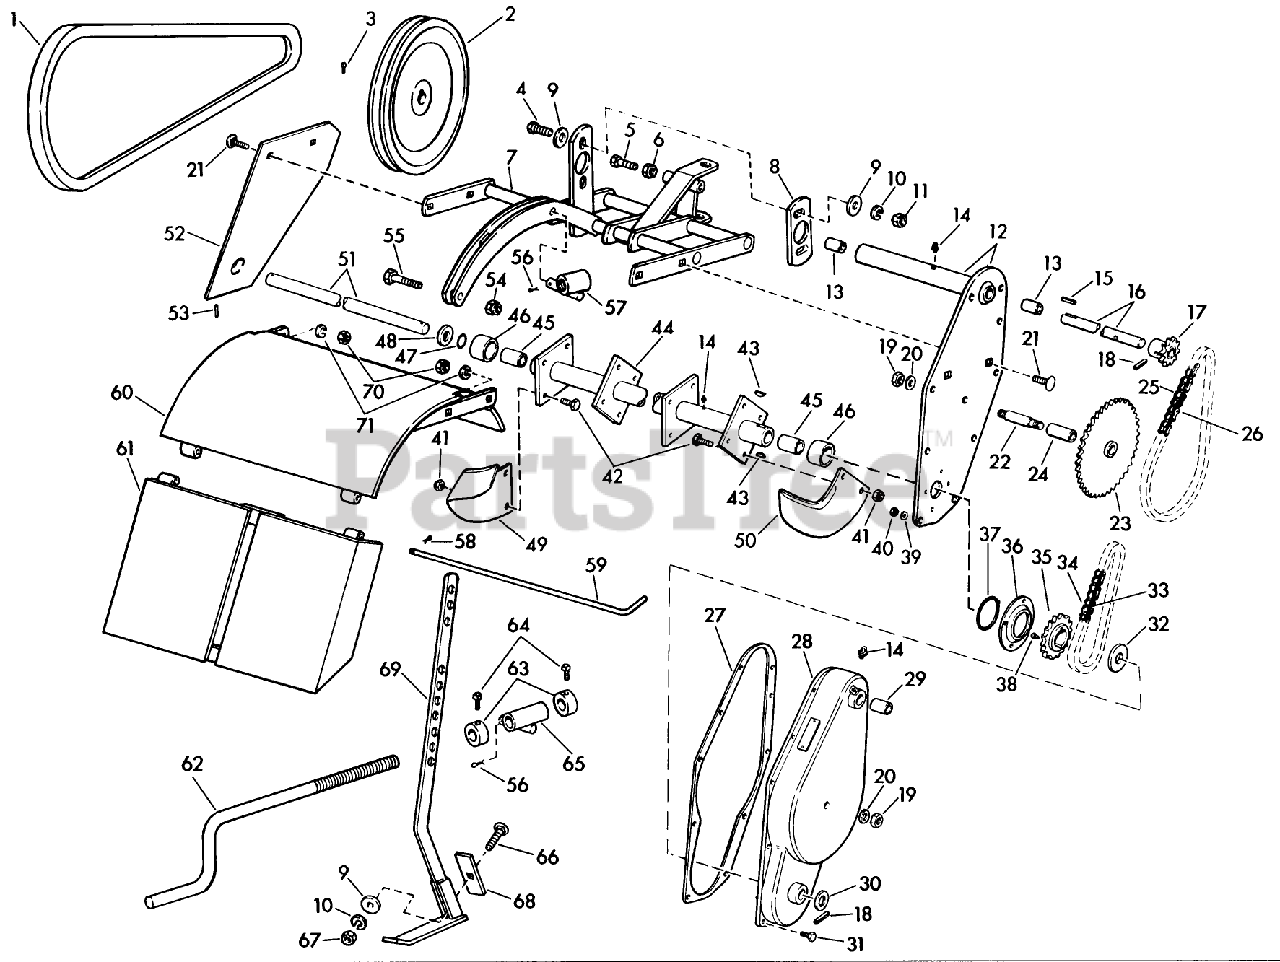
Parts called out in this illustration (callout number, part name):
1	V Belt 60" A Section
2	Pulley 10.4 OD A Section
3	Set Screw
4	Capscrew 5/16-18 x 7/8 Lg.
5	Capscrew 3/8-16 x 1 Lg.
6	Hex Nut 3/8-16
7	Frame Assembly
9	BAR-LIFT LINK *R
10	Lockwasher
11	Hex Nut
12	Back Plate Assembly
14	Grease Fitting
16	Input Shaft
17	Input Sprocket and Hub Assv.
18	Roll Pin
19	Hex Jam Nut
20	Lockwasher, Shakeproof
21	PEDAL-BRAKE *R
22	Intermediate Shaft
23	Sprocket Cluster Assy
24	Bushing
25	Chain #41-1/2 Pitch, 55 Links
28	Cover Assembly
31	Capscrew
32	Thrust Washer
33	Extension-Chute
36	Oil Seal Retainer
38	Self Tapping Screw #8-32 x 1/4 Lg.
40	Hex Nut
44	Rotor Tube Assembly
49	Tine LH
51	Rotor Shaft
52	Side Plate Assembly
53	Roll Pin
55	Capscrew 3/8-24 x 2 Lg.
56	Cotter Pin 1/8 x 1-1/2 Lg.
57	Adjusting Screw Nut
58	BUMPER-RUBBER
60	Hood Assembly
61	Hood Board Assembly
63	Set Collar 5/8 ID
64	Set Screw 5/16-18
65	Bearing Assembly
67	Hex Nut 5/16-18
68	Adjustable Shovel
69	Depth Shoe Assembly
